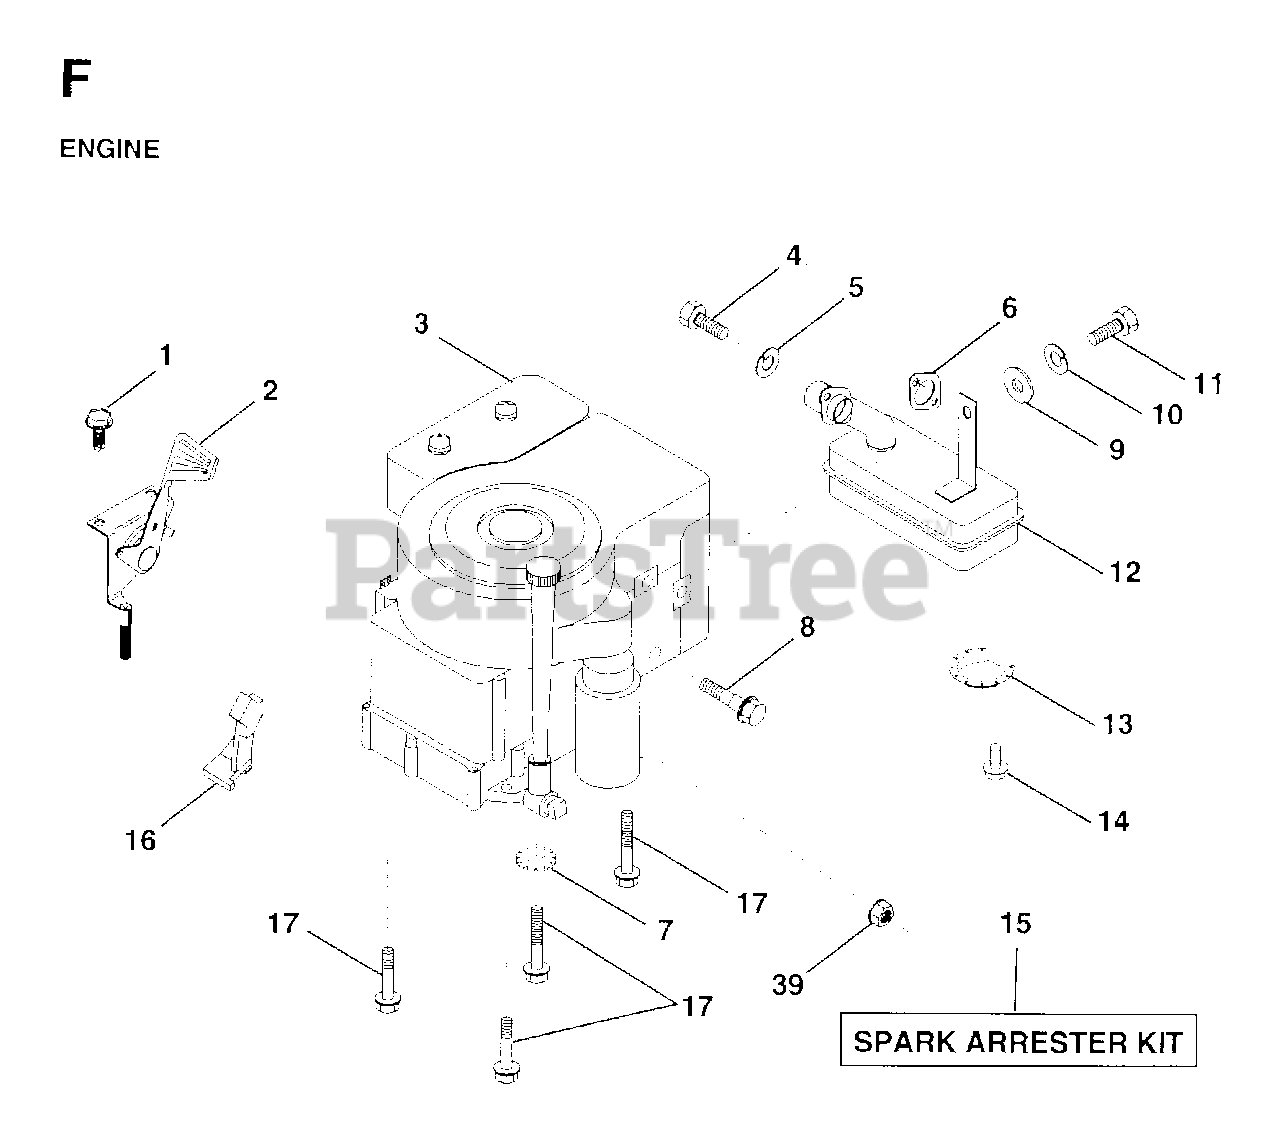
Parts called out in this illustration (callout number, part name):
2	THROTTLE CONTROL
4	SCREW
5	LOCKWASHER
6	GASKET ENG
7	LOCKWASHER
9	WASHER
10	LOCKWASHER
13	DEFL MUFFLER LTV
14	SCREW
15	ARRESTER SPARK (OPTIONAL)
16	STOP THROTTLE
17	SCREW LT
39	NUT FLANGE 1/4-20 STARTER NUT
